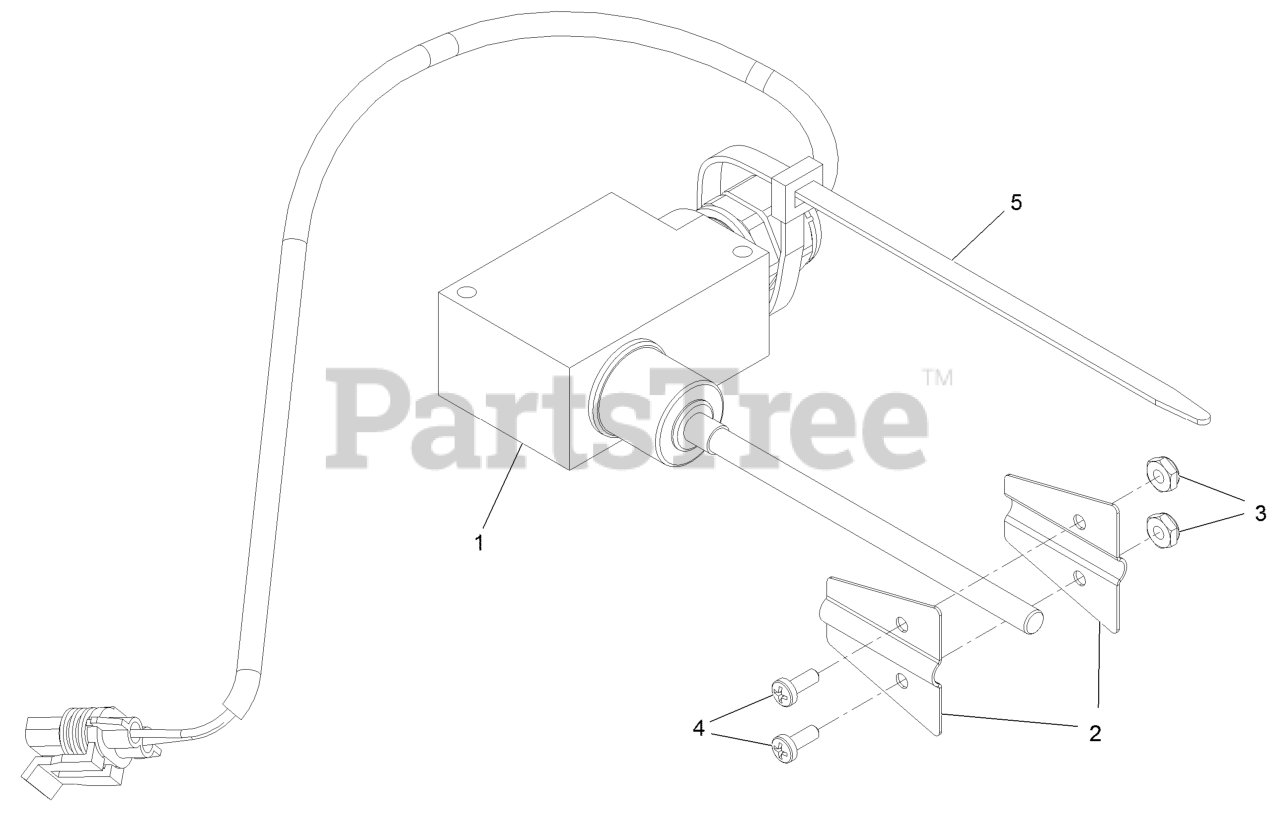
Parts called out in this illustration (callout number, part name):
1	FILL SENSOR WIRE KIT
2	FLAG- SENSOR, FILL
3	NUT-HEX
4	SCREW-PAN
5	TIE-PLASTIC
